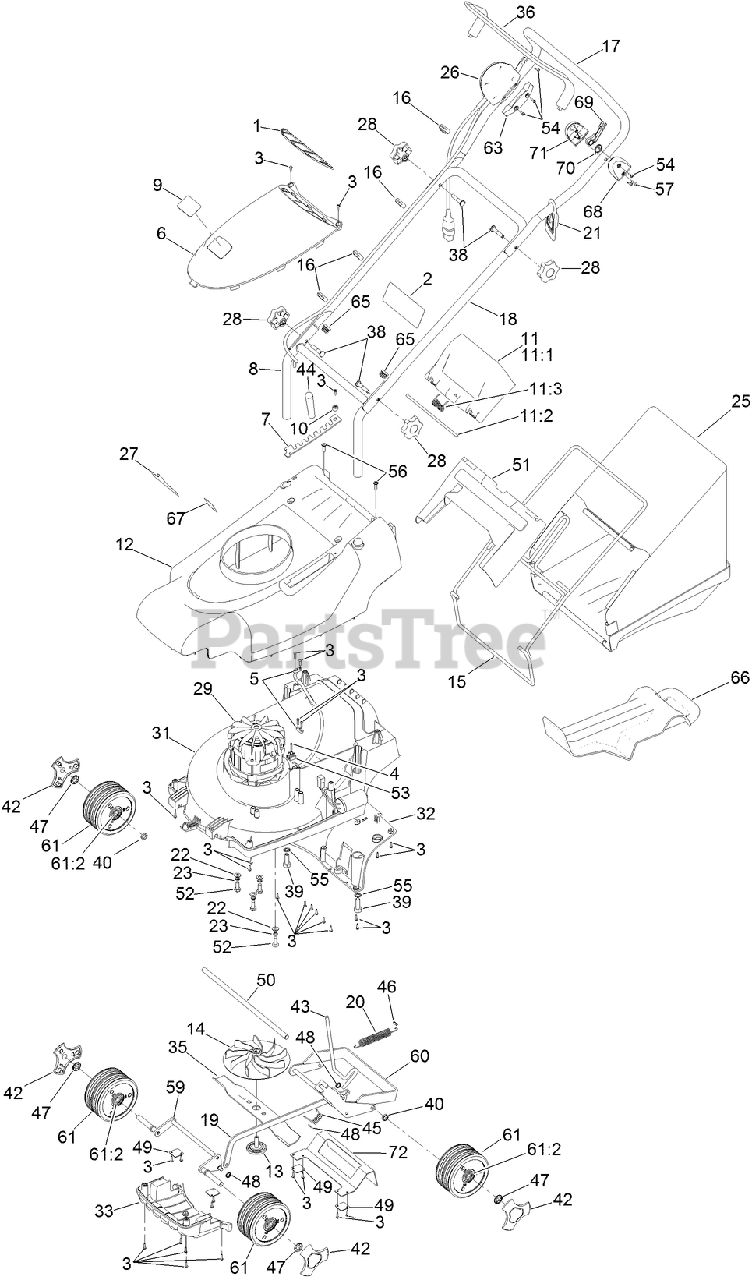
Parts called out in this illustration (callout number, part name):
1	VENT MESH ASM
2	DECAL-SAFETY, ELECTRIC
5	CLAMP-CABLE
6	COVER-MOTOR
7	PLATE-HOC
8	HANDLEBAR-LOWER
9	DECAL-TORO
10	COVER-SCREW, HOC
11	Rear Flap ASM
11:1	DEFLECTOR-REAR
11:2	ROD-DEFLECTOR
11:3	SPRING-DEFLECTOR
12	COVER-TOP
13	BOLT-FIXING, CUTTERBAR (NYLON)
14	CARRIER-CUTTERBAR
15	FRAME-GRASSBAG
16	CLIP-CABLE
17	HANDLEBAR-UPPER
18	HANDLEBAR-MIDDLE
19	ROD-CONNECTING
20	SPRING-BALANCE, COUNTER
21	CLEAT-CABLE
22	WASHER
23	WASHER-SPRING
25	GRASSBAG
26	SWITCH AND LEAD ASM
28	KNOB-HANDLEBAR
31	UNDERDECK
32	THROWPLATE
35	CUTTERBAR
36	ARM-BAIL
38	BOLT-HANDLEBAR
39	SCREW-HH
40	SPACER-WHEEL, REAR
42	CAP-HUB
43	LEVER-HOC
44	KNOB-HOC
45	SPRING-HOC
46	PIN-SPRING, HOC
47	WASHER-STARLOCK
48	WASHER-STARLOCK
49	PLATE-PIVOT, AXLE
50	ROD-AXLE, REAR
51	TOP-GRASSBAG
52	BOLT-MOTOR
53	BLOCK-TERMINAL
55	WASHER
56	SCREW
57	SCREW-PPH
59	FRONT AXLE ASM
60	REAR AXLE ASM
61	WHEEL ASM
61:2	BEARING-WHEEL
63	SWITCH-LEFT, LOWER
65	PLUG-TUBE
66	PLUG-MULCHING
67	DECAL-HOC
68	MOUNT-LEFT
69	LEVER-MOUNT
70	SPRING-BAILARM
71	MOUNT-RIGHT
72	GUARD-PLATE, AXLE
